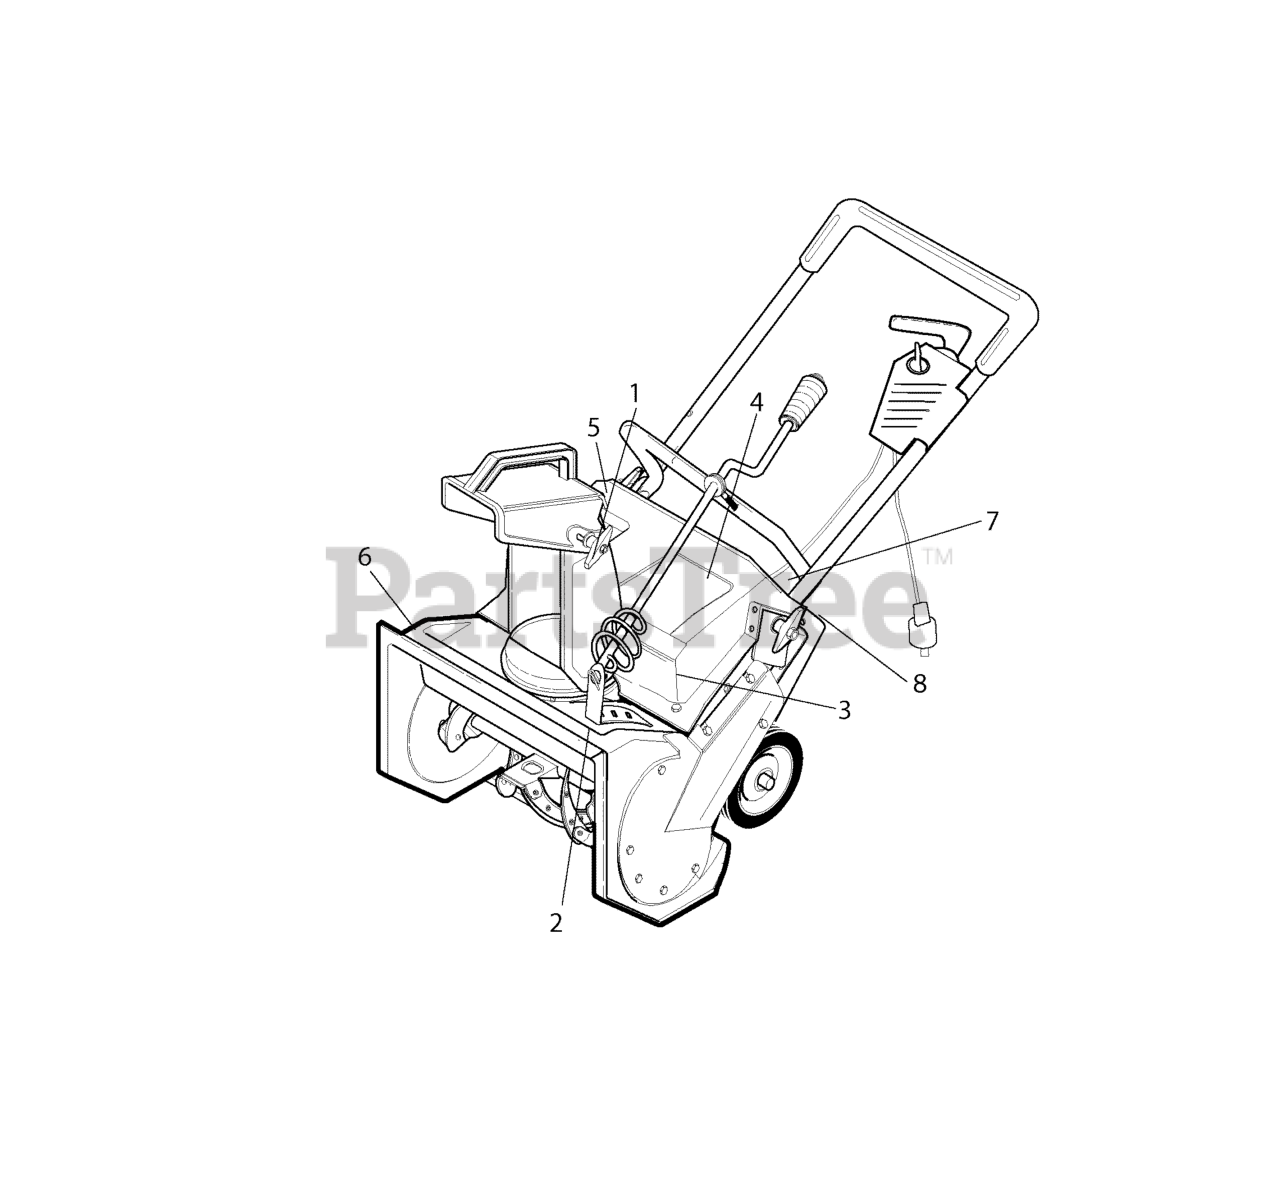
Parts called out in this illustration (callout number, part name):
1	DECAL, DANGER CHUTE FR/EN
2	DECAL, DANGER AUGER FR/EN
3	DECAL, 12 AMP/20"
4	DECAL, DANGER READ MANUAL
5	DECAL, 20" ELECTRIC BILING
6	DECAL, DANGER CHUTE 20 ELECTRIC
7	DECAL, WARNING/CAUTION
8	DECAL, WARNING CUTOUT PRT F/E
